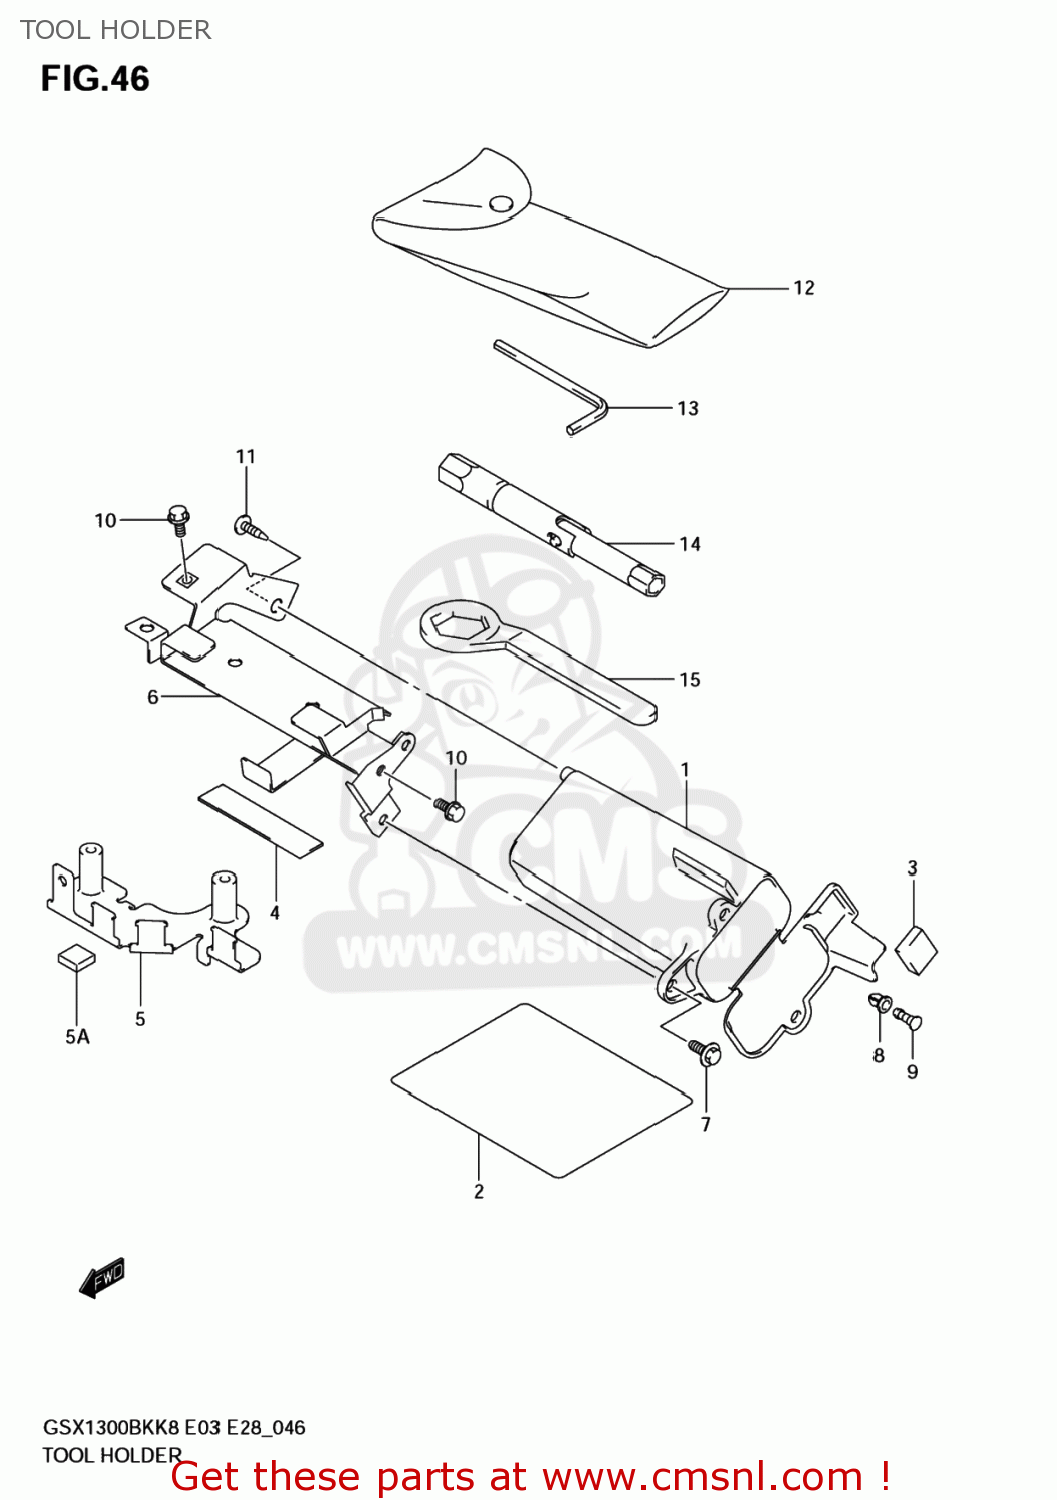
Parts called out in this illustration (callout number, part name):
1	HOLDER,TOOL
2	SHIELD,TOOL HOLDER
3	CUSHION,TOOL HOLDER LID
4	PROTECTOR(20X90)X2
5	HOLDER ASSY,ELECTRIC PARTS
5A	CUSHION,SIDE
6	BRACKET,TOOL HOLDER
7	BOLT(6X16.5)
8	GROMMET
9	PLUNGER
10	BOLT
11	SCREW
12	TOOL ASSY
13	SPANNER,HEXAGON(6)
14	SPARK PLUG WRENCH
15	RING SPANNER(36)
